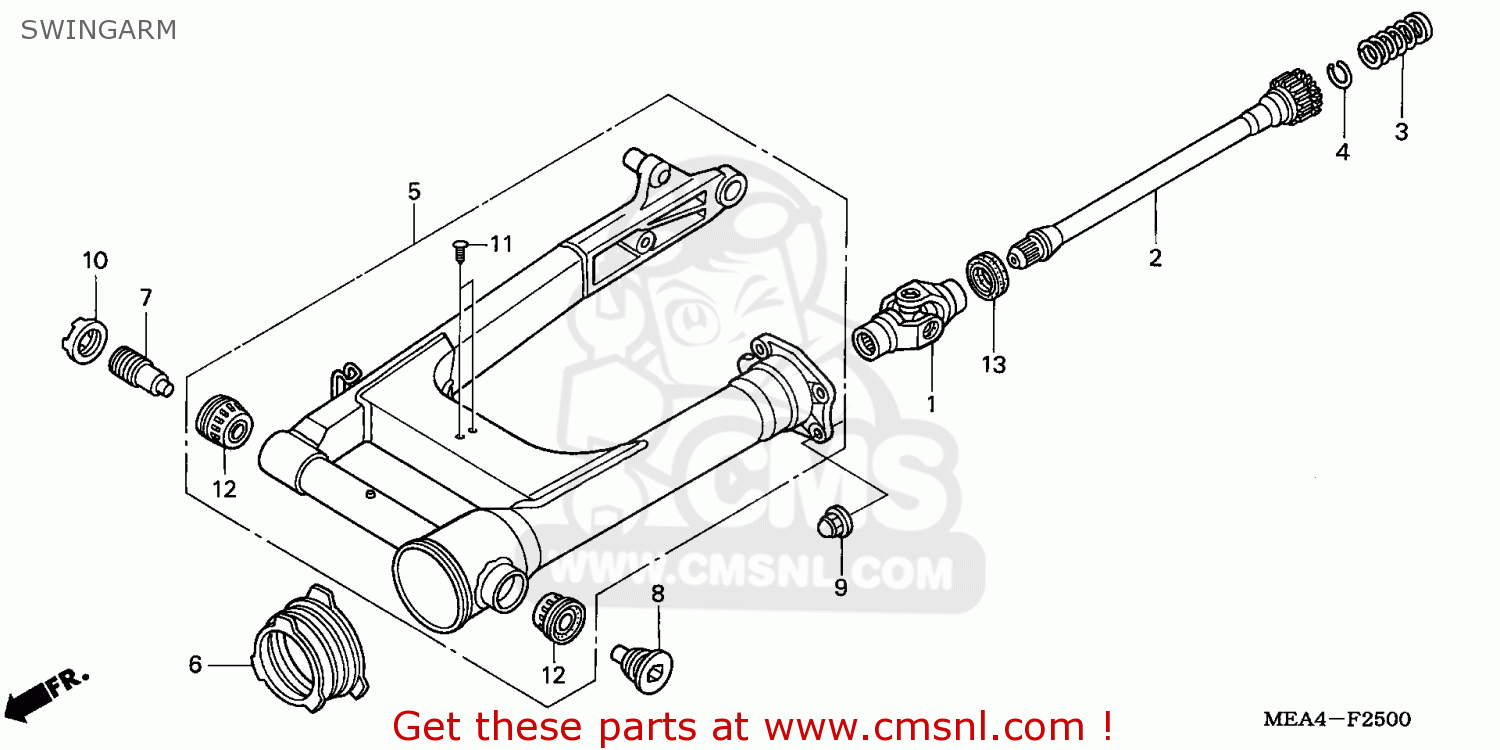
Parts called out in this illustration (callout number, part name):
1	JOINT COMP,YOKE
2	SHAFT,PROP
3	SPRING,SHAFT
4	RING,STOPPER
5	SWINGARM ASSY,RR
6	BOOT,JOINT
7	BOLT R,SWINGARM P
8	BOLT R,SWINGARM P
9	NUT HEX,CAP 10MM
10	NUT,RR.FORK PIVOT
11	CLIP
12	BRG,TAP.17X40X13.
13	OIL SEAL,27X43X7
